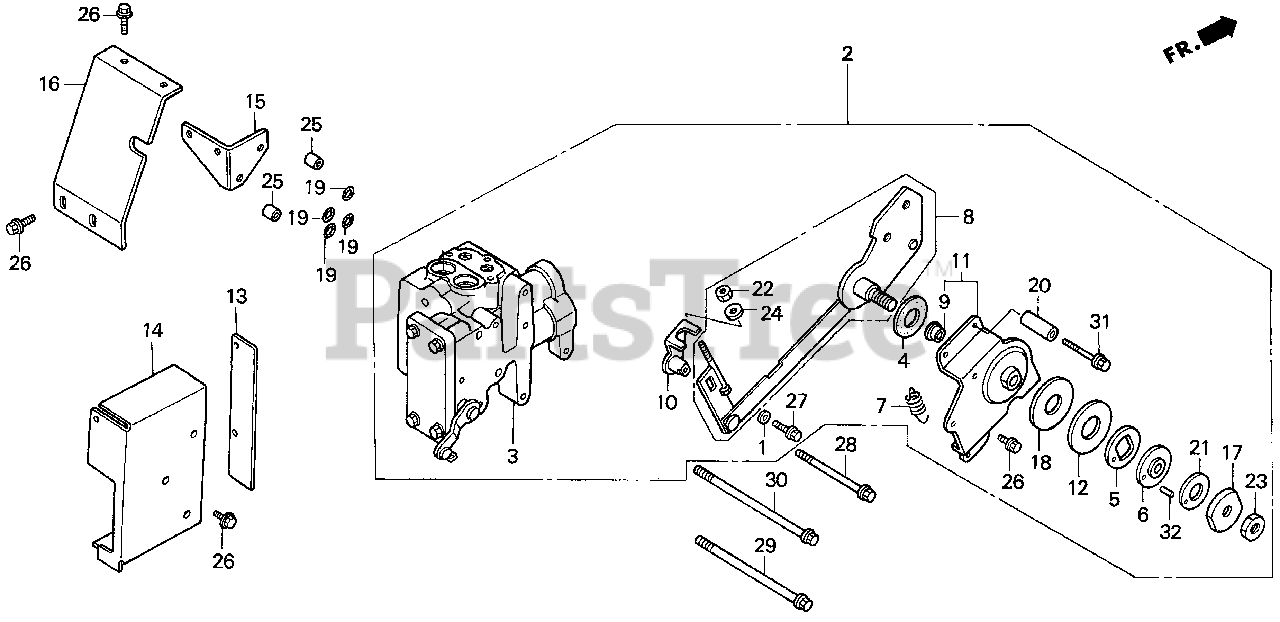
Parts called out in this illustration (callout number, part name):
1	SPACER, HOSE CLAMP (NOT AVAILABLE)
2	VALVE ASSY., MECHANICAL POSITION CONTROL
3	VALVE ASSY., POSITION
4	WASHER, FRICTION
5	WASHER A, POSITION CONTROL ARM
6	WASHER B, POSITION CONTROL ARM
7	SPRING, POSITION CONTROL RETURN
8	LINK, POSITION CONTROL
9	BUSH (14X10)
10	SUPPORT, POSITION CONTROL JOINT
11	BASE, POSITION CONTROL LINK
12	SPRING, CONED DISK (22MM)
13	PLATE A, POSITION CONTROL COVER
14	PLATE B, POSITION CONTROL COVER
15	BRACKET, LINK COVER
16	COVER, LINK
17	NUT (10MMX6)
18	WASHER, THRUST (22X45X0.8)
19	O-RING (15.8X2.4)
20	COLLAR (6.1X13X28)
21	WASHER, THRUST (16X30X1.5)
22	NUT, HEX. (6MM)
23	NUT, HEX. (10MM)
24	WASHER, PLAIN (6MM)
25	PIN A, DOWEL (10X16)
26	BOLT, FLANGE (6X12)
27	BOLT, FLANGE (6X20)
28	BOLT, FLANGE (8X80)
29	BOLT, FLANGE (8X120)
30	BOLT, FLANGE (8X130)
31	BOLT, FLANGE (6X40)
32	ROLLER (2X8)
